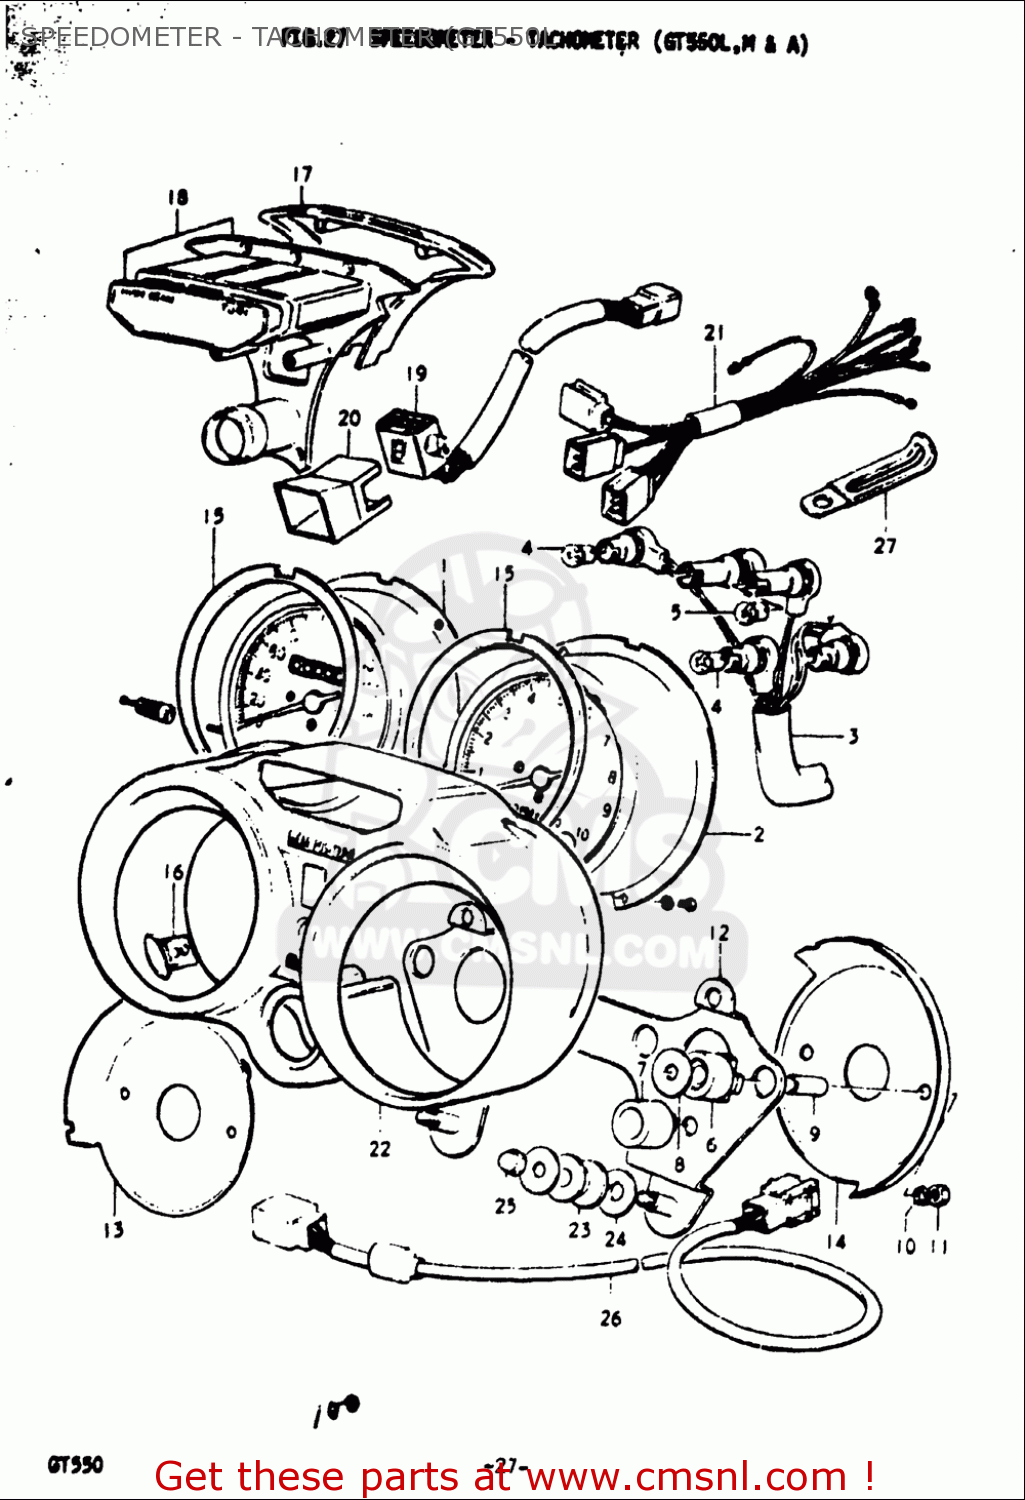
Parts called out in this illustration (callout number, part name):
4	BULB(12V3.4W,STANLEY,A72A)
5	BULB(12V1.7W,A71A)
6	CUSHION,METER NO.1
7	CUSHION,METER
8	WASHER(5.5X16X1.5)
10	WASHER,LOCK
11	NUT
16	CAP
23	CUSHION
24	WASHER(6.5X18X1.6)
25	NUT
27	CLAMP(L:65)
